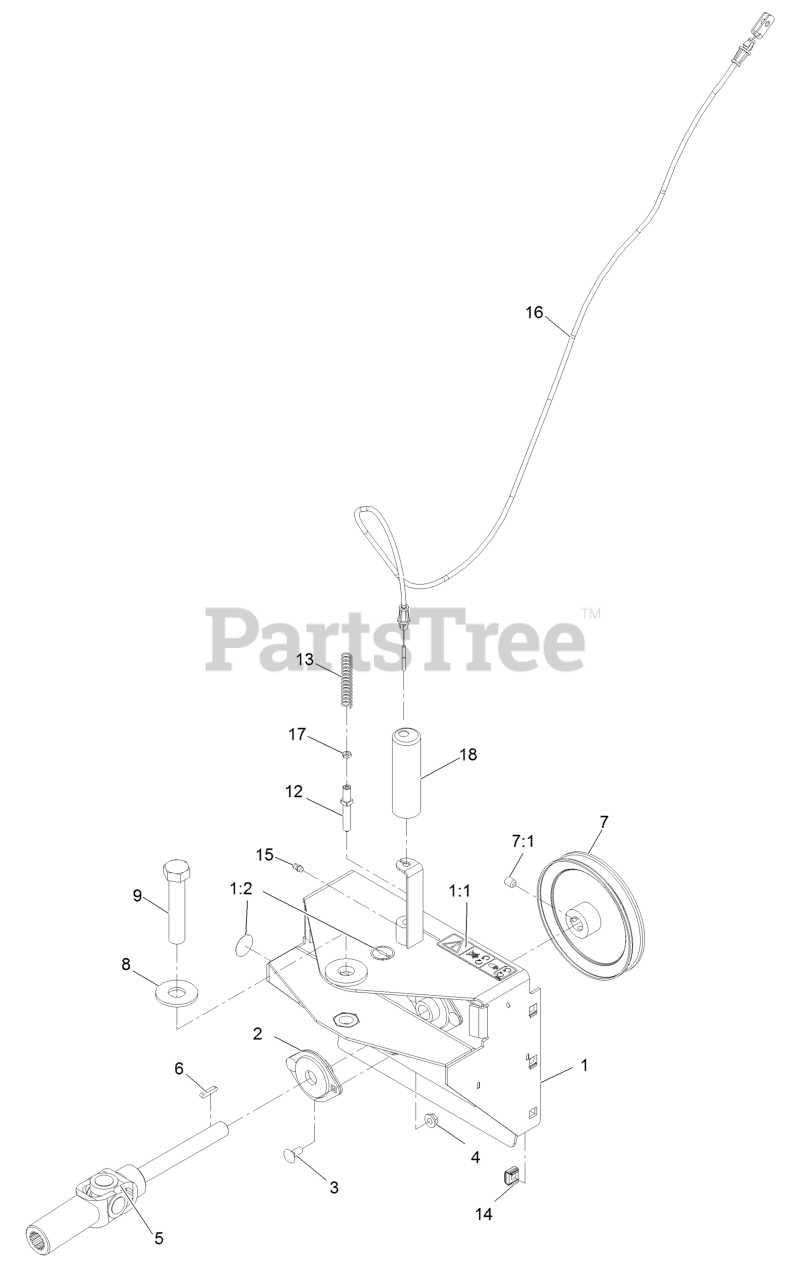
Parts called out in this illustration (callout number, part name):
1	Broom Mounting Frame ASM
1:1	Decal-Missing, Cover
1:2	Decal-Grease
2	Bearing-Shaft
3	Bolt-Carriage 5/16-18 X 3/4
4	Nut-Whizlock 5/16-18
5	Shaft-Drive
6	Key-Round End
7	Pulley-Impeller
7:1	Setscrew-5/16-18 X 3/8
8	Washer
9	Screw-HH 3/4-16 X 3 3/4
12	Pin-Swing
13	Spring-Compression
14	Nut-Retainer
15	Zerk-1/4-28 Str
16	Cable-Angle, Broom
17	Nut-Hex
